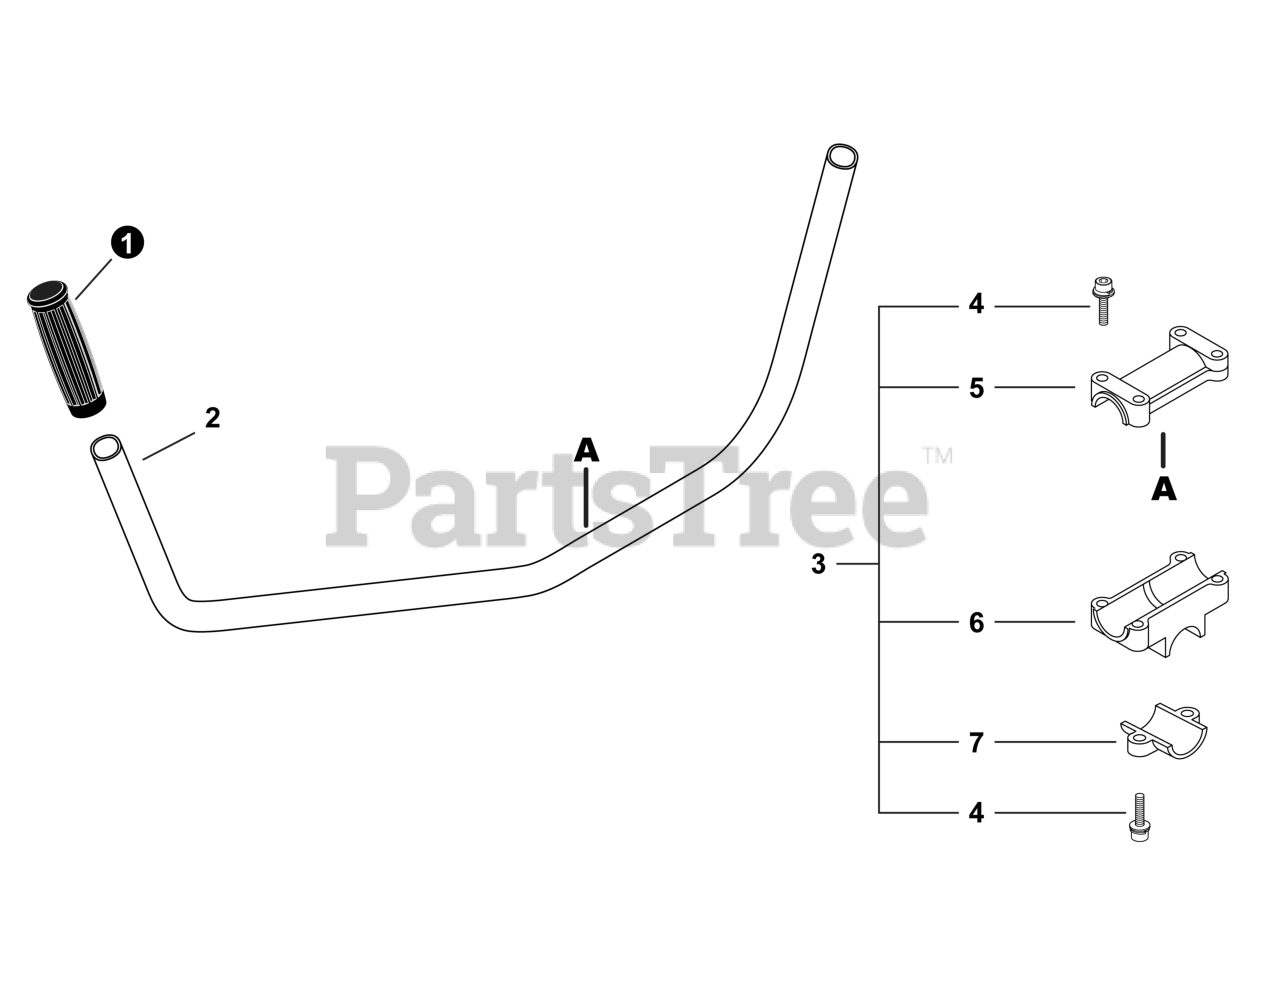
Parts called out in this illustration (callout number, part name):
1	GRIP, HANDLE
2	HANDLEBAR
3	BRACKET ASSY, HANDLE
4	BOLT 5x25
5	BRACKET, UPPER
6	BRACKET, LOWER
7	BRACKET, MOUNTING
